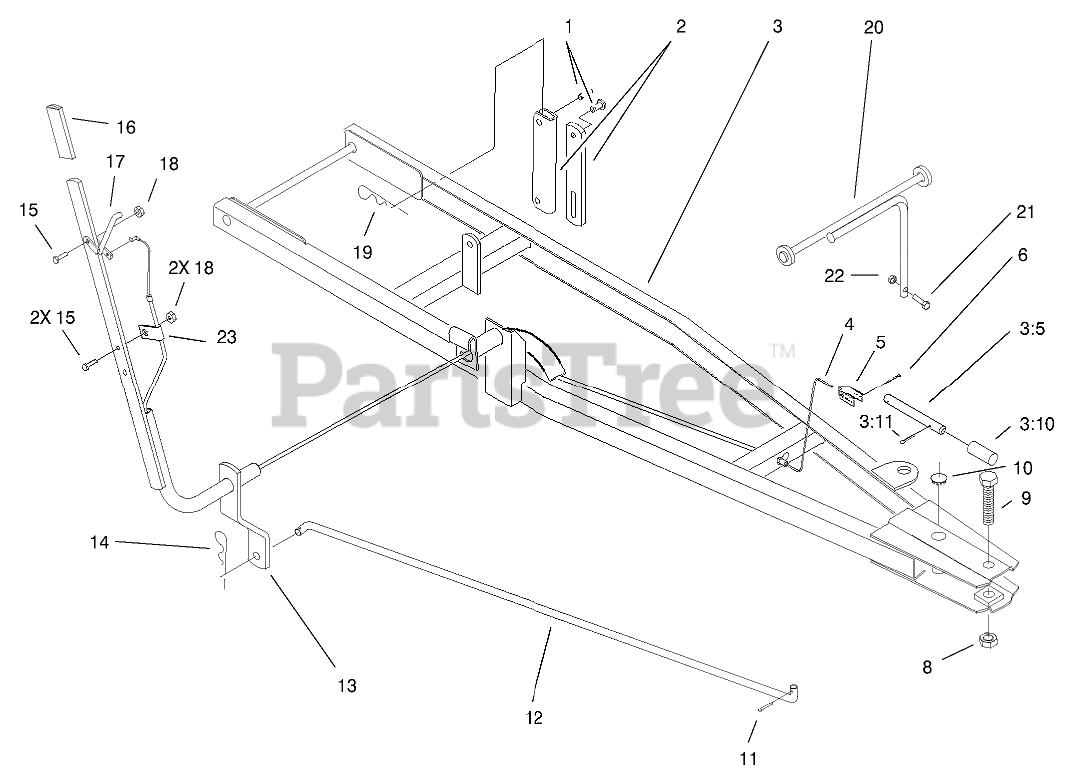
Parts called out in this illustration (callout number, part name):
1	PIN-CLEVIS
1	PIN-WELD
2	LINK - LIFT
3:5	PIN-INDEX
3:10	SPRING-COMPRESSION
3:11	PIN-COTTER
4	CABLE-INDEXING
5	BRACKET - CABLE END
6	PIN-COTTER
8	NUT-LOCK
9	SCREW-HH
10	PLUG
11	PIN-COTTER
12	ROD - BLADE CONTROL
13	LEVER-INDEXING
14	PIN-HAIR
15	SCREW-HH
16	GRIP
17	LEVER
18	NUT-LOCK
19	PIN-HAIR
20	STABILIZER
21	SCREW-HH
22	NUT-LOCK, NI
23	R-CLAMP
